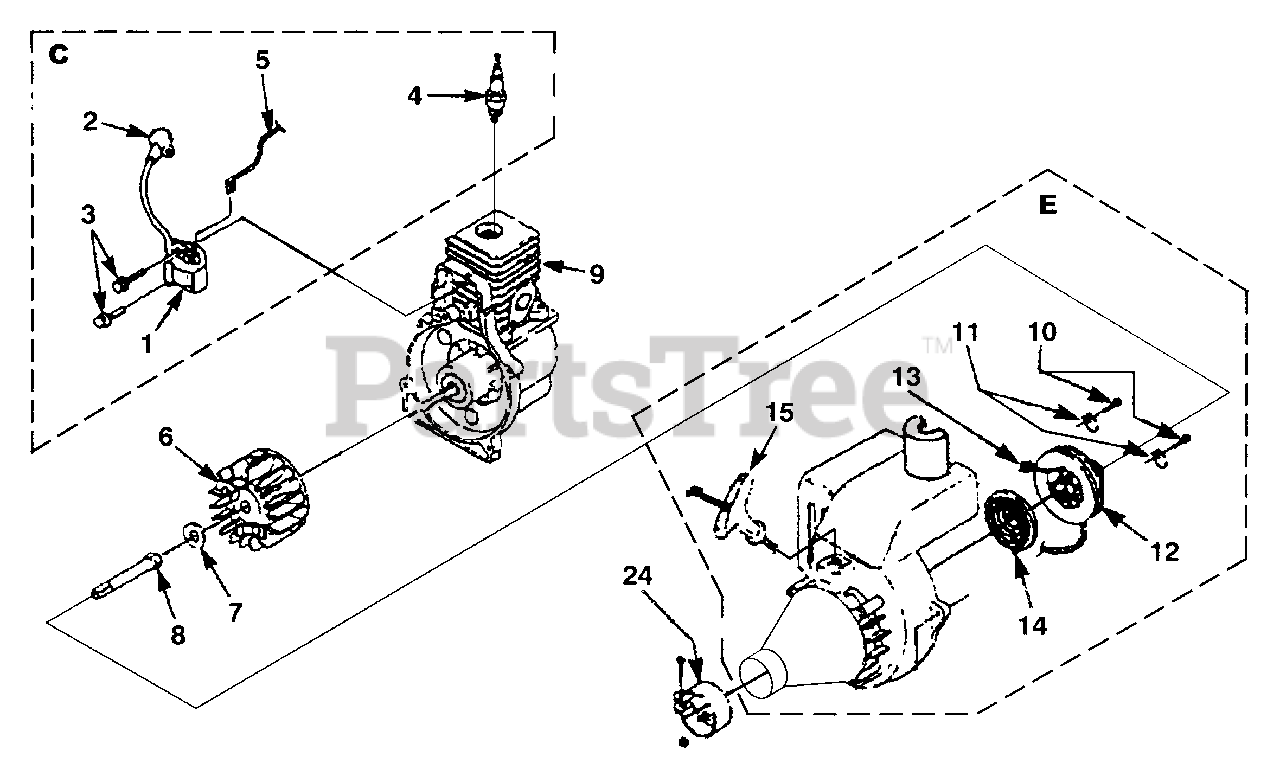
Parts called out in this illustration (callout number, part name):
1	MODULE - Ignition
2	TERMINAL & COVER
3	SCREW - Taptite (8-32 X 1")
4	SPARK PLUG
5	LEAD - Electrical
6	ROTOR KIT
7	WASHER - Flat
8	CONNECTOR - Drive
9	SHORT BLOCK
10	SCREW - Plastite (#10-1/2")
11	BRACKET - Retaining
12	PULLEY - Starter
13	ROPE - Starter (42")
14	SPRING & CONTAINER
15	GRIP - Starter
C	IGNITION KIT
E	COMPLETE STARTER ASSEMBLY
